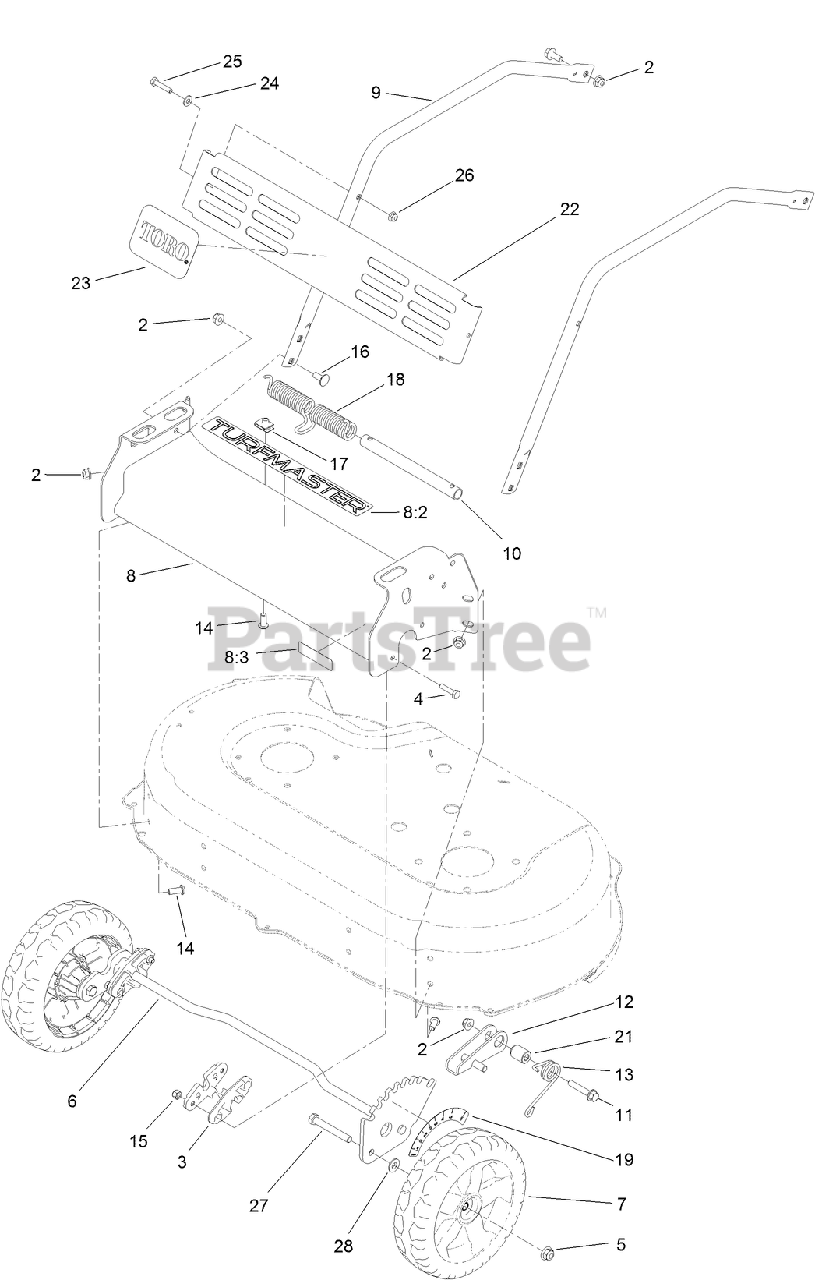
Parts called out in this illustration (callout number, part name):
2	NUT-HF, NI
3	BUSHING-FRONT
4	SCREW-HH
5	NUT-HF, NI
6	AXLE-FRONT
8	FRONT BUMPER ASM
8:3	DECAL-WARNING
10	MANDRELL-SPRING
11	SCREW-HWH
12	LOCK-HEIGHT, ADJUSTMENT
13	SPRING-TORSION
14	SCREW-HSBH
15	NUT-LOCK, NI
16	SCREW-CARR
17	NUT-U
18	SPRING-TORSION
19	DECAL-HOC, FRONT
21	SPACER
24	WASHER-FLAT
25	SCREW-HH
26	NUT-HF
27	SCREW-HH
28	SPACER-COVER, WHEEL
